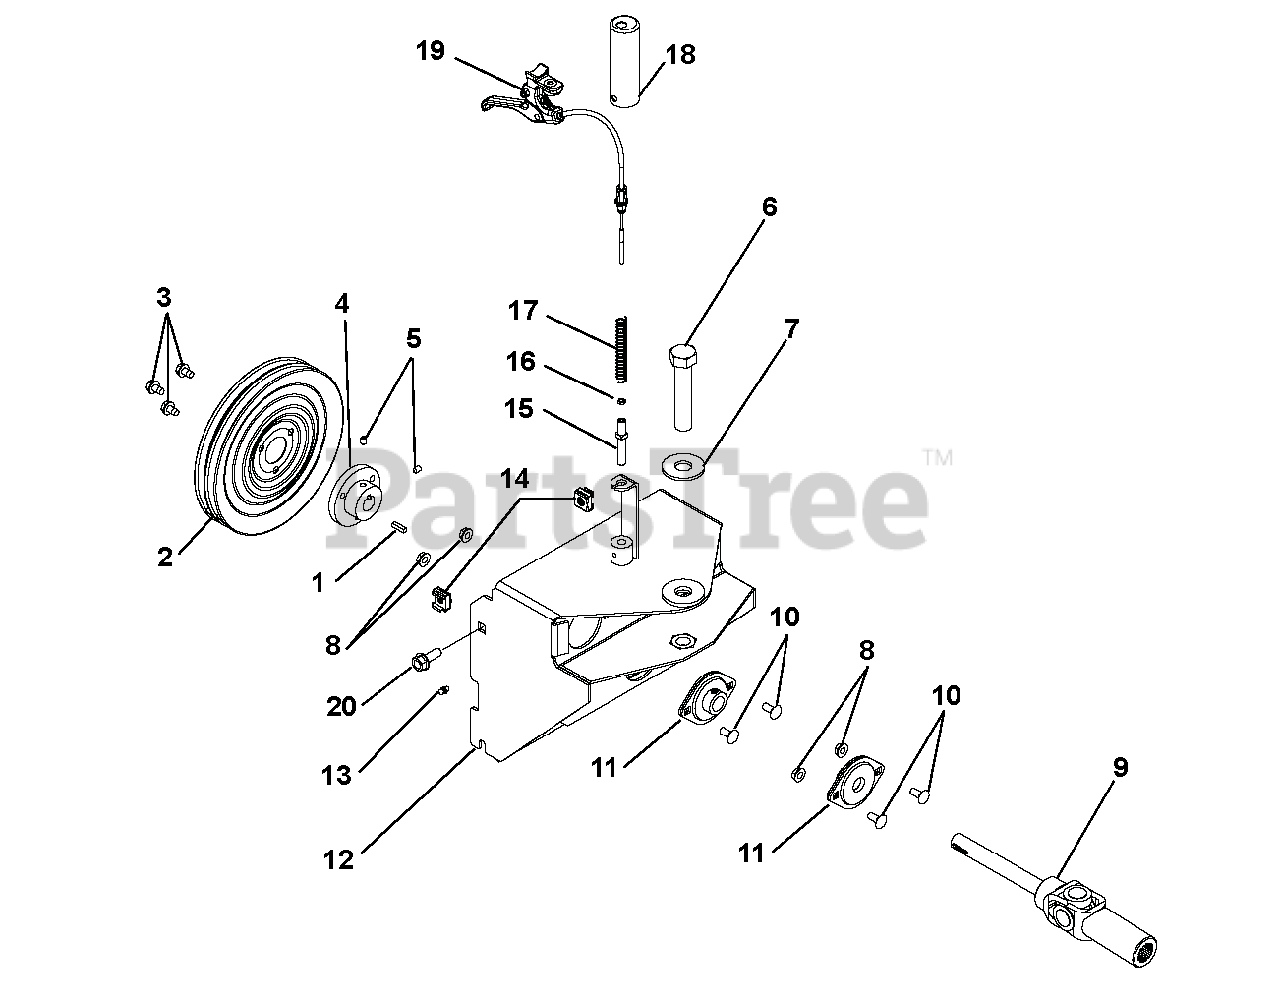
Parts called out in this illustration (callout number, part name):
1	KEY-SQ .188X.75X.188
2	PULLEY, SPIN FORM DUAL GROOVE
3	@SCR-TAP .31-18X.50 HWH TR YWZ
4	HUB, PULLEY
5	SCR-SET .25-20X.38 SKHCUPNL OH
6	HHCS .75-16 UNF X 3.75
7	@WSHR-FL-STL.812X2.00X.148YWZC
8	@NUT-LK-TOP-FLG .31-18 YWZC
9	DRIVELINE, SERIES 07
10	@BLT-RDHDSQNK .31-18X.75 G5YZ
11	BEARING, 3/4" FLANGETTE
12	MTG FRAME, MCD ARIENS
13	FTG-LUBE .25-28X.256 YWZC
14	NUT-RETNR .38-16 TINRMAN
15	PIN, SWING MCD-TRIGGER RELEASE
16	@NUT-HEX 10-24 YWZC
17	SPRING, COMPRESSION .51"X3.5"
18	CAP, VINYL MODIFIED
19	CABLE, CONTROL SWING-MCD
20	BLT-SERHFWH .38-16X.75 YWZC
